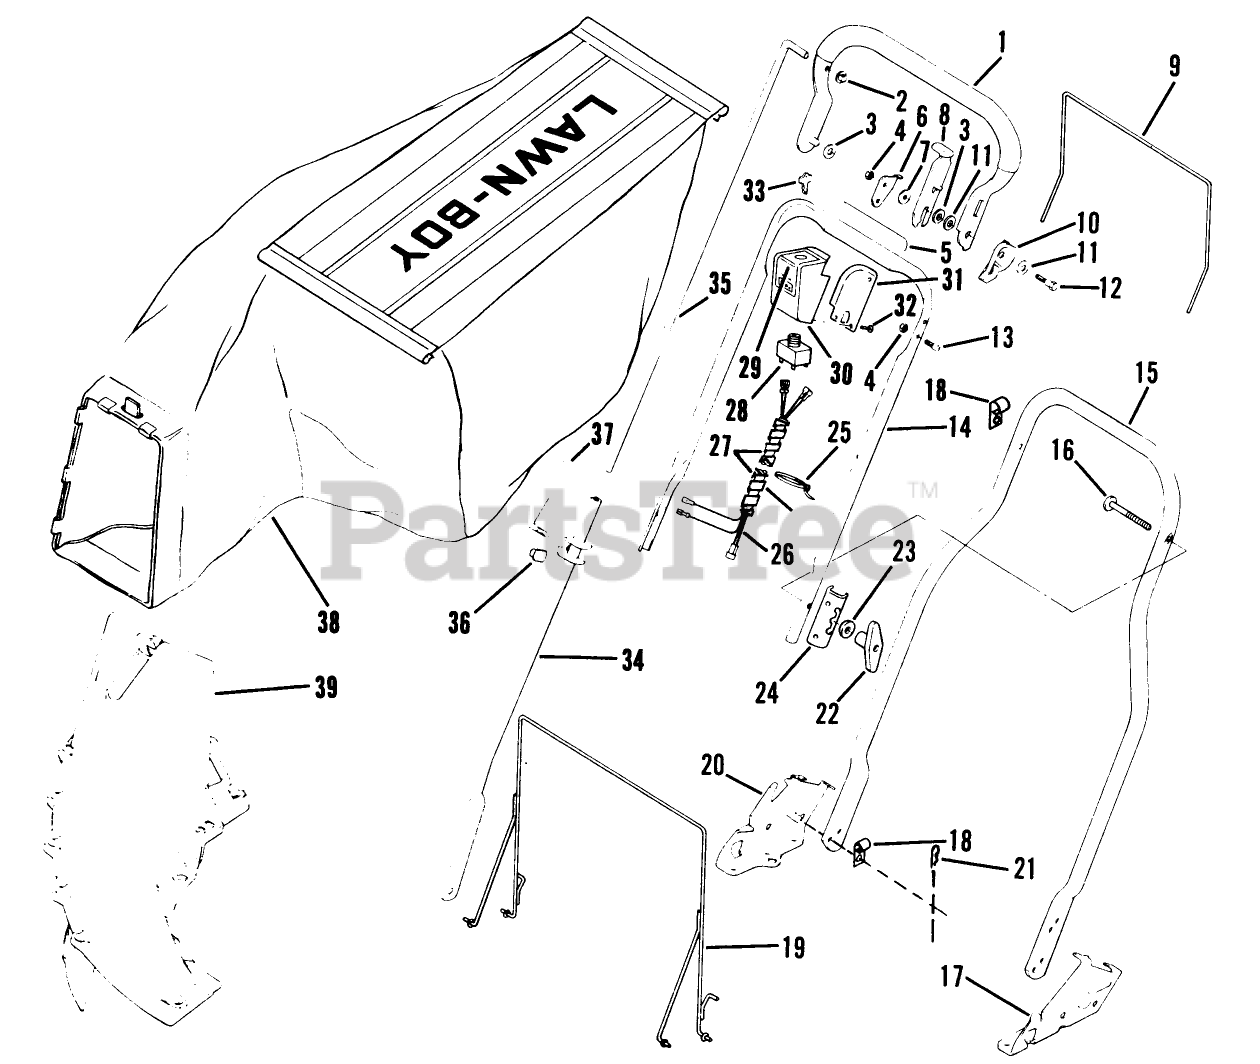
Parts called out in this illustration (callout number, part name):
3	WASHER M
4	LOCKNUT E
6	HANDLE STOP
7	WASHER
8	LEVER LOCKOUT
9	HANGER
12	BOLT PIONEER
13	SCREW-HANDLE STOP
14	HANDLE
20	HANDLE BRACKET
21	HAIR PIN
22	NUT-WING
23	WASHER-CURVED
24	BRACKET R/B 613462
30	HOUSING SWITCH
35	ROD CONTROL
